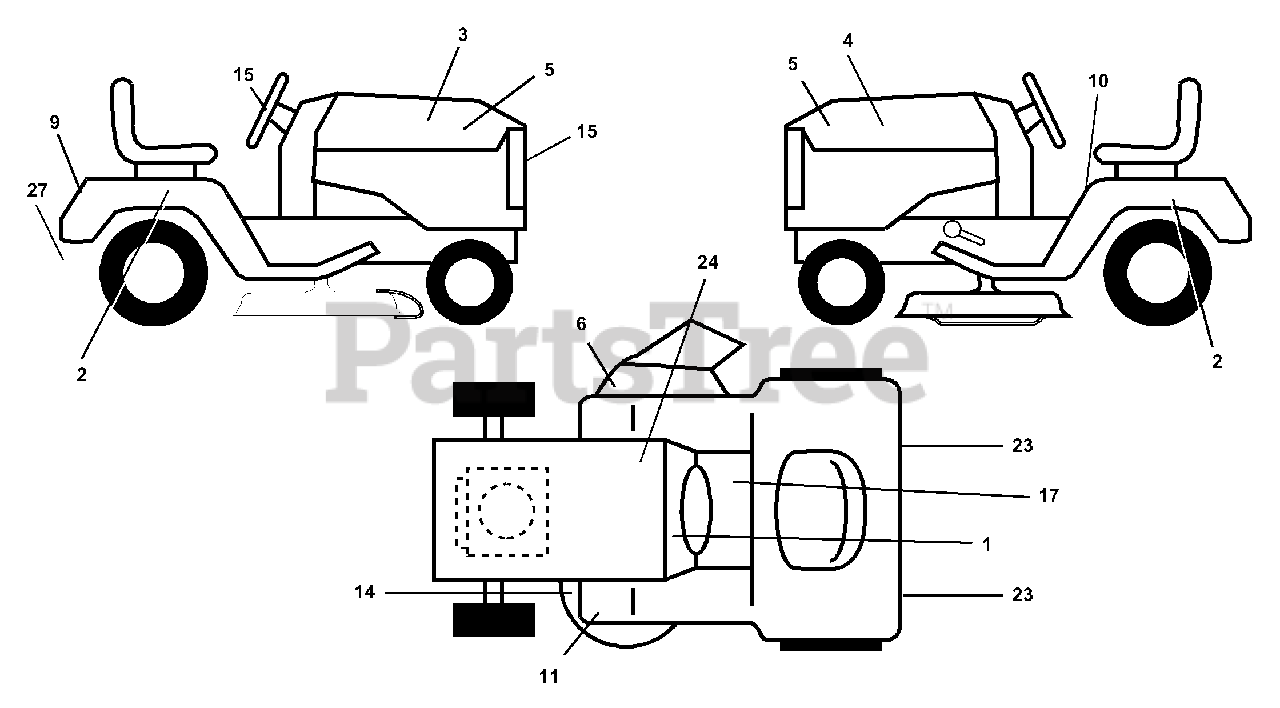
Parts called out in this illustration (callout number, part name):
1	Decal, Operating Instruction
2	Decal, Fender Auto
3	Decal, Hood, RH
4	Decal, Hood, LH
5	Decal, Side Panel
6	Decal, Warning
9	Decal, Fender
10	Decal, Danger
11	Decal, Clutch/Brake
14	Decal, V-Belt Schematic
15	Decal, Ins. Strg Whl
17	Decal, Saddle Brake Parking
23	Reflector, Taillight
24	Decal, Btry Dngr/Psn
27	Decal,Drawbar
